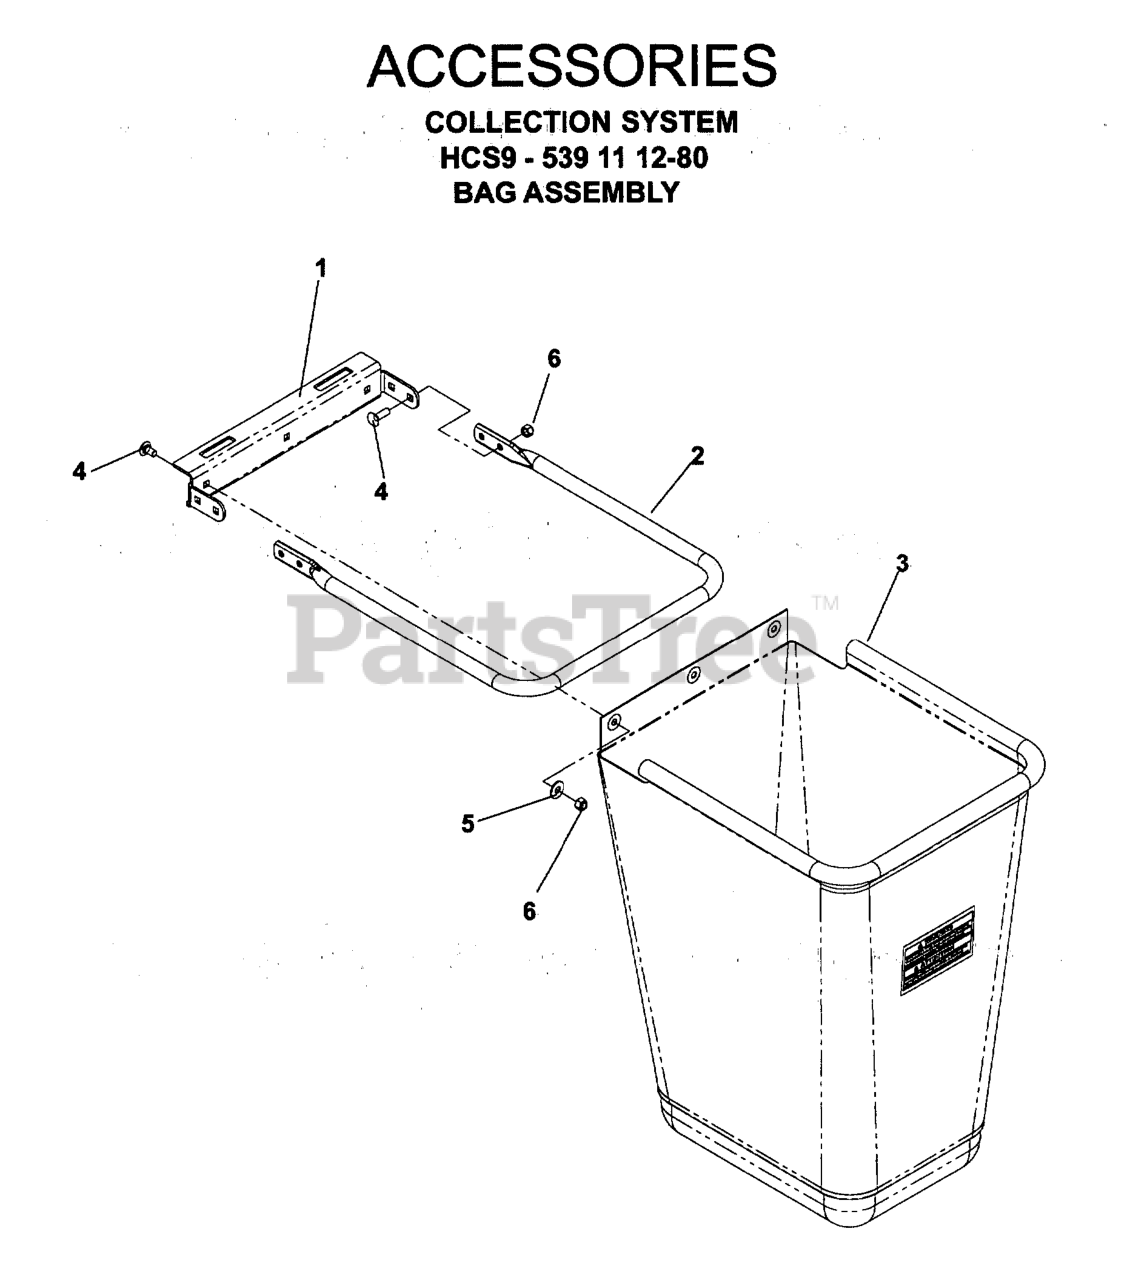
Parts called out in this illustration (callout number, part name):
1	HANGER, BAG
2	TUBE BAG FRAME
3	BAG, SMALL
4	BOLT 5/16C X 3/4" CARRIAGE
5	WASHER 5/16 FLAT
6	NUT 5/16 NYLOC
